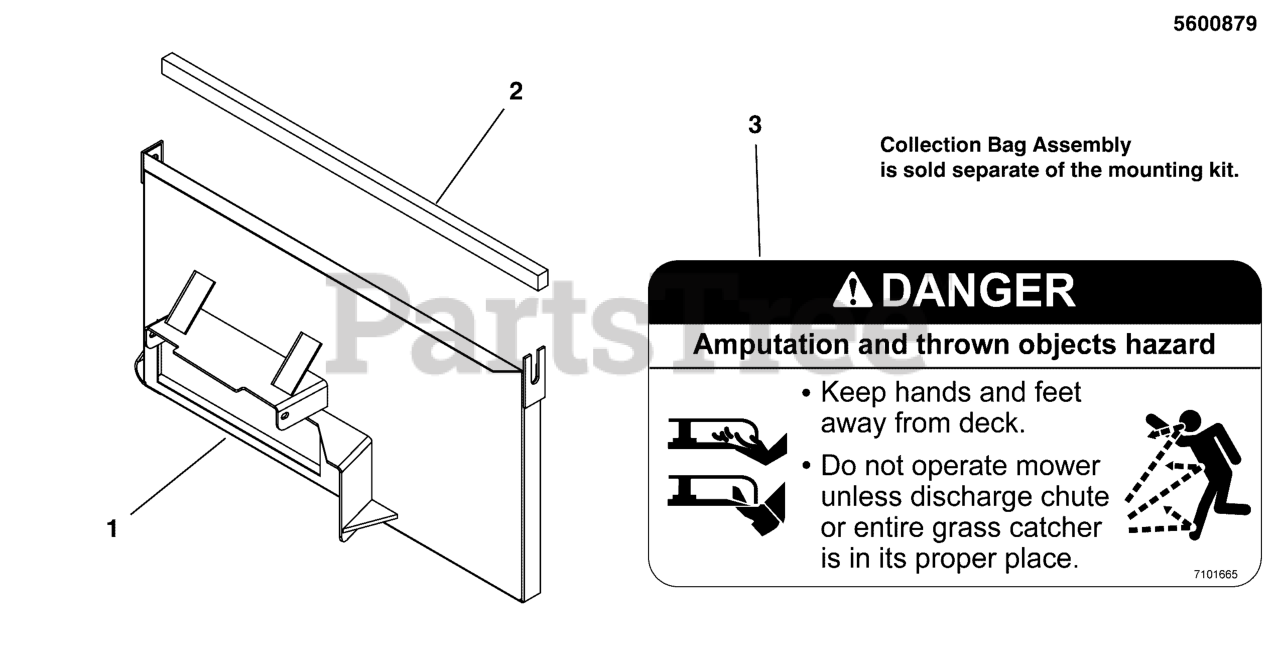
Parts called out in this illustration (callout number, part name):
1	WELD, BAGGER MOUNT, 36 - BLACK
2	FOAM, 3/4 X 1 X 28.25
3	DECAL, DANGER DO NOT OPERATE W/O DEFLECT
